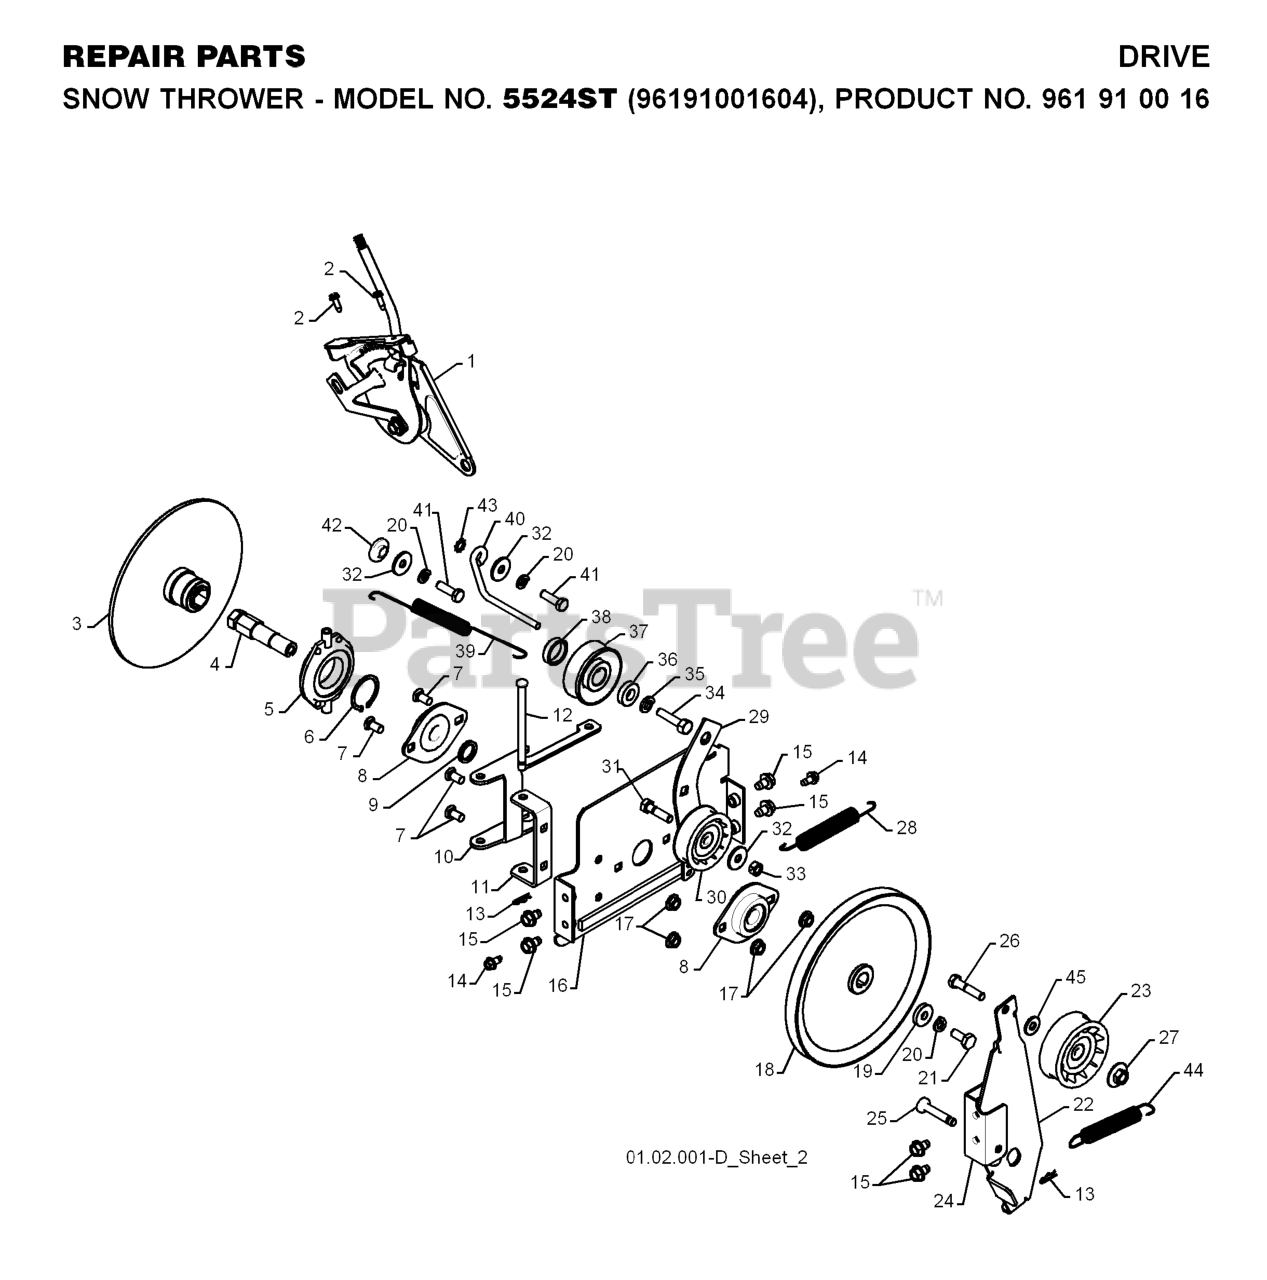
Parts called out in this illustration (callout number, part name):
1	HEAD ASSY SPEED
2	SCREW #10-24 X 5/8
3	DRIVE PLATE WELDMENT
4	SHAFT.HEX.SHORT
5	TRUNNION BEARING ASSY
6	RETAINING RING (2 2)(3 2)
7	BOLT
8	BEARING FLANGE
9	SPACER, BEARING
10	LEVER.SHIFTER.PLATE.BLACK
11	BRACKET, SHIFTER SUPPORT
12	PIN, PIVOT LEVER
13	RETAINER CLIP PM
14	SCREW
15	Screw 5/16-18 x 1/2 Hex, Self Tapping 5/16-18 x 1/2
16	PLATE.DRIVE.MOUNTING.BLACK
17	NUT.FLANGE.5/16
18	PULLEY.TRACTION.7.75
19	WASHER, FLAT
20	WASHER.LOCK.HVY.HLCL.SPR.5/16
21	Screw, Hex Head 5/16-18 x 3/4
22	ARM.IDLER.BRAKE
23	PULLEY.W/SPACER.2.75
24	BRACKET, IDLER PIVOT
25	PIN, IDLER PIVOT
26	HEX BOLT
27	LOCKNUT 5/16-18
28	RP SPRING, TRACTION IDLER
29	ARM, IDLER
30	PULLEY.W/SPACER.2.25
31	BOLT.5/16-18X1-1/4 FULL.THREAD
32	STEEL WASHER
33	NUT.CENTERLOCK.5/16-
34	SCREW, HEX HD 3/8-24 X 1-3/8
35	LOCKWASHER
36	WASHER, FLAT 3/8
37	PULLEY,ENGINE TRACTION DRIVE
38	SPACER.ENGINE.PULLEY
39	SPRING.RETURN
40	BELT.GUIDE.RH
42	RP BUSHING, IDLER PIVOT
43	WASHER EXT TOOTH LOCK 5/16
44	SPRING, BRAKE
45	WASHER.20X8.5
